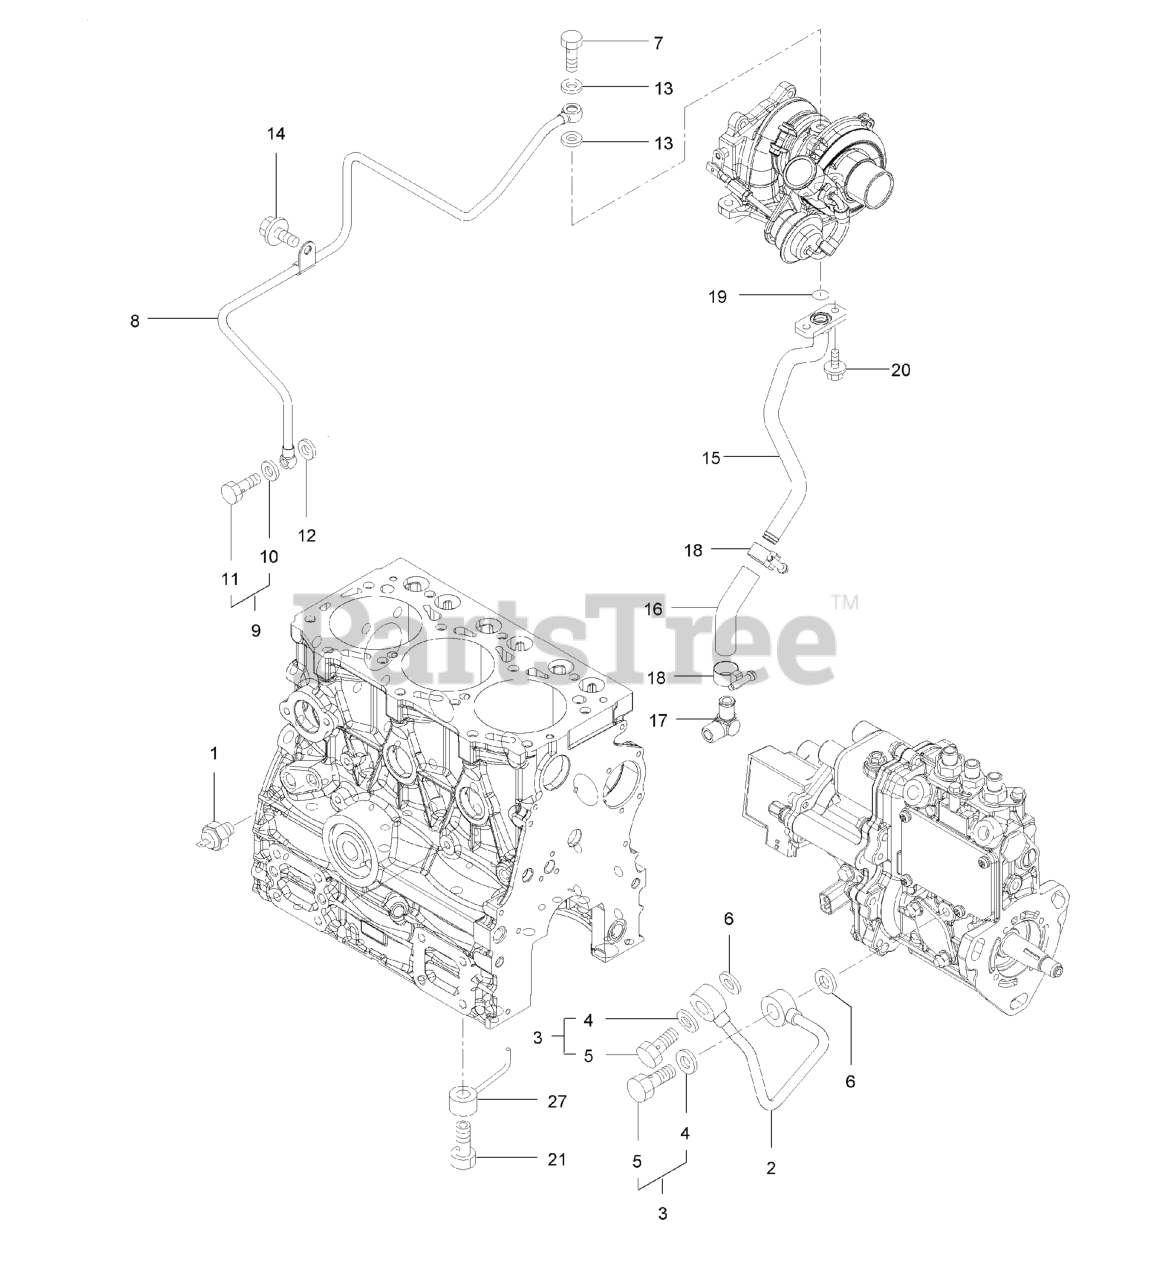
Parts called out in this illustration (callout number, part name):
1	SWITCH-OIL
2	PIPE-OIL
3	JOINT BOLT ASM
4	WASHER-SEAL
5	BOLT-JOINT
6	WASHER-SEAL
7	BOLT-JOINT, PIPE
8	PIPE ASM-LO
9	JOINT BOLT ASM
10	WASHER-SEAL
11	BOLT-JOINT
12	WASHER-SEAL
15	PIPE-LO RETURN
18	CLAMP-HOSE
21	VALVE ASM-CHECK
27	NOZZLE ASM-PISTON
